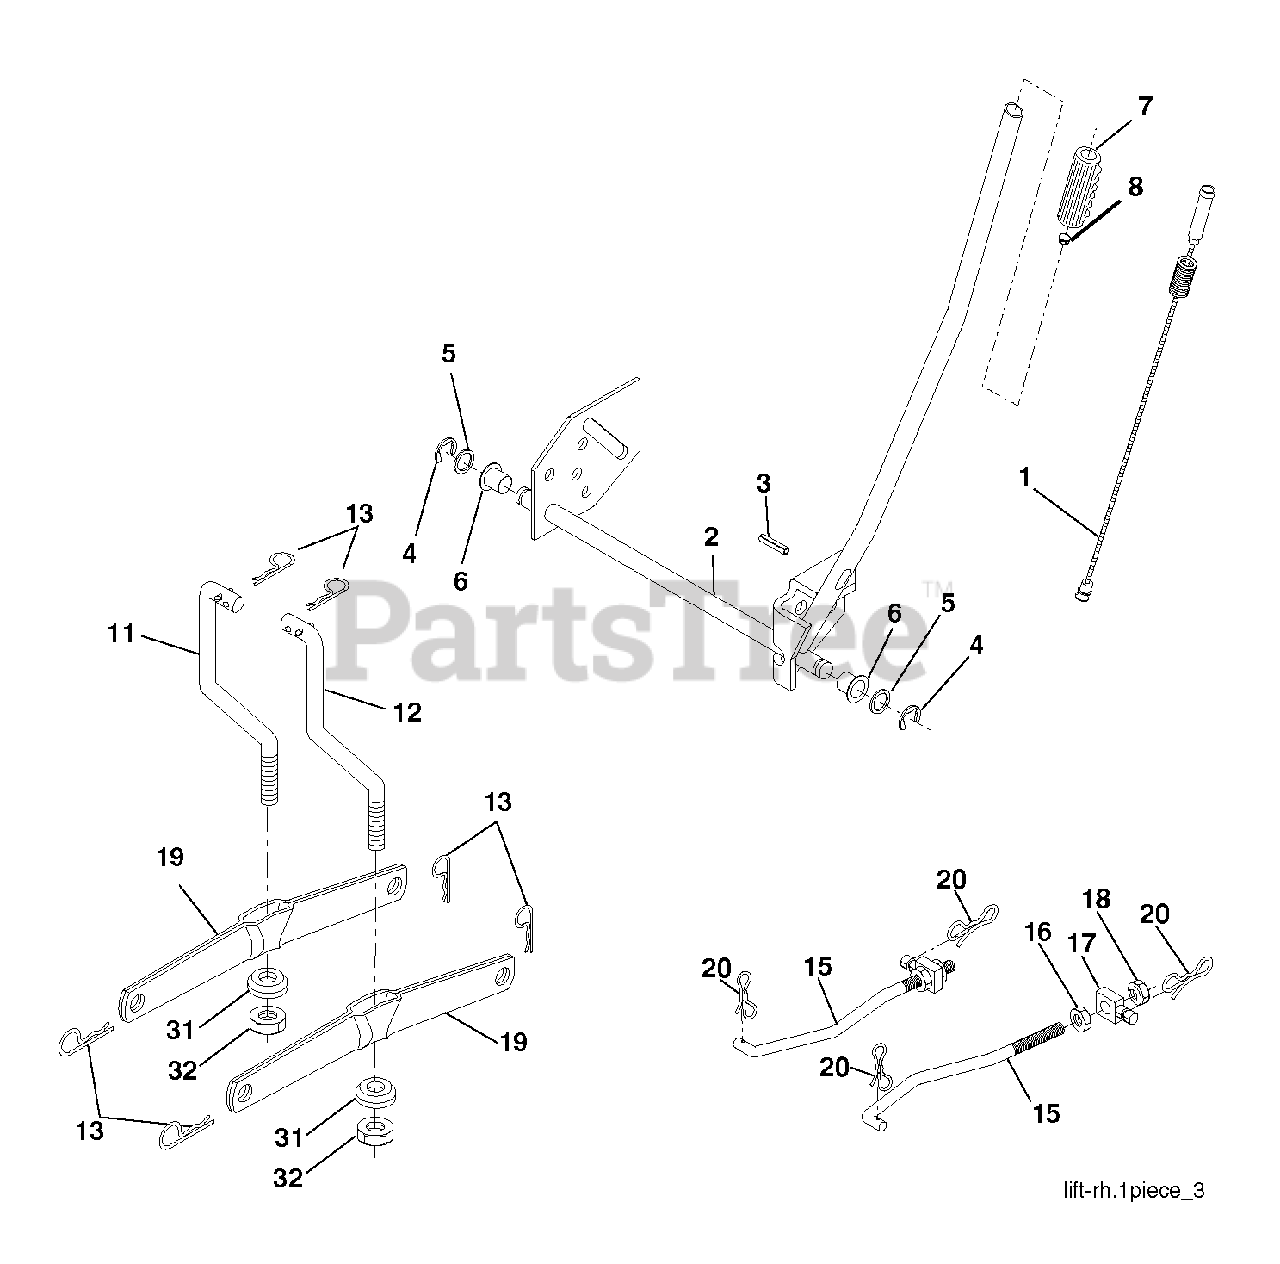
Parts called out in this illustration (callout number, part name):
1	PLUNGER.ASM.LIFT.LEVER.BLK.
2	SHAFT.ASM.LIFT.YT
3	PIN.GROOVE.5/16
4	RETAINING RING LT
6	BEARING.NYLON
7	GRIP
8	PLUNGER BUT KIT
11	LINK LIFT LH
12	Lift Link Assembly, RH
13	RETAINER-SPRNG RB
15	LINK.SUSPENSION.FRONT
16	NUT.HEX.JAM.1/2-13
17	TRUNNION
18	NUT.LK.W/WSH.1/2.
19	ARM.REAR.SUSPENSION
20	PIN.COTTER.7/16.BOW TI.
31	BEARING.PIVOT.LIFT
32	NUT CROWNLOCK 3/8-24
